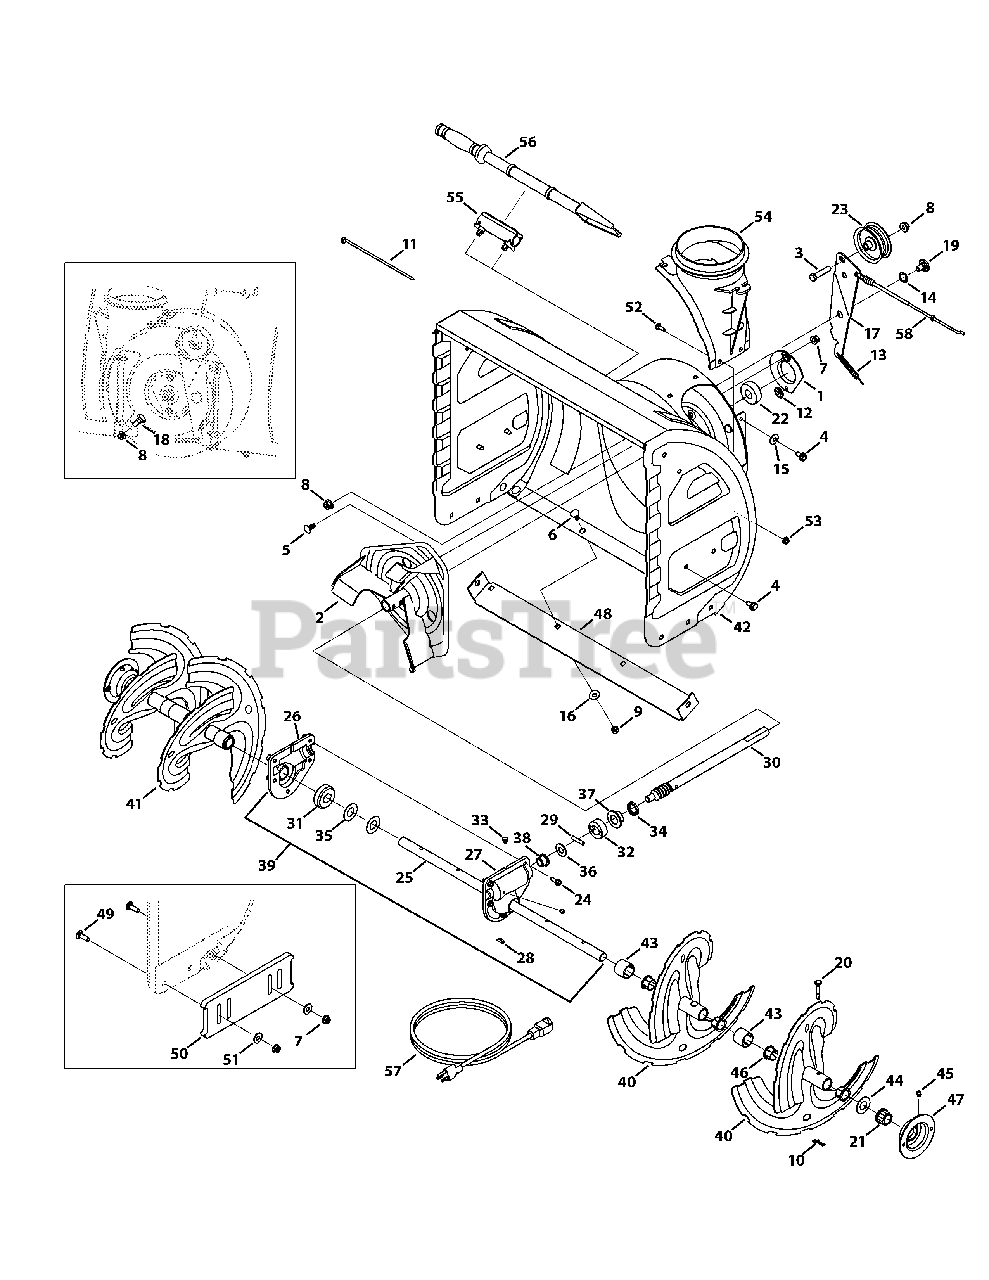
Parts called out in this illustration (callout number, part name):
1	Taptite Screw, 1/4-20 x .750
2	Impeller Assembly, 12" Dia.
3	Hex Screw, 3/8-16 x 1.75
4	Taptite Screw, 5/16-18 x .750
5	Carriage Bolt, 5/16-18 x .750, Grade 5
6	Carriage Bolt, 5/16-18 x .750, Steel
7	Flange Lock Nut, 5/16-18
8	Flange Lock Nut, 3/8-16
9	Hex Nut, 5/16-18
10	Bow-Tie Cotter Pin
11	Cable Tie
12	Push-On Nut, .25 Dia.
13	Extension Spring, .38 OD x 4.59
14	Wave Washer, .625 x .885 x .0175
15	Washer, Bell, .340 x .872 x .060
16	Bell Washer, .340 x .872 x .060, Steel
17	Auger Axle, 26"
18	Shoulder Bolt, 3/8-16 x .496 x .336
19	Shoulder Screw, 3/8-16 x .625 x .17
20	Shear Pin, .25 x 1.50
21	Hex Flange Bearing x .75 ID
22	Flange Ball Bearing, .75 ID x 1.85 OD
23	Flat Pulley, 2.75 OD
24	Bearing Housing, 1.85 ID
25	Auger Idler Bracket
26	Housing Assembly, RH
27	Housing Assembly, LH
28	Hi-Pro Key, 3/16 x 5/8
29	Dowel Pin, .25OD x 1.25
30	Worm Shaft, .75 OD
31	Worm Gear, 20T
32	Thrust Collar, .756 ID x .600
33	Plug, 1/4 x .437
34	Oil Seal, .75 x 1.131 x .188
35	Flat Washer, .760 ID x 1.50 OD
36	Flat Washer, .51 x 1.12 x .06
37	Flange Bearing, .75 ID x 1.00 OD x .59
38	Flange Bearing, .50 ID x .75 OD x .59
39	Gear Box Assembly, 26"; (Incl. Ref. 1, 17, 26 - 38)
40	Spiral Assembly (Left)
41	Spiral Assembly (Right)
42	Auger Housing, 26" Cub
43	Spacer, 1.25OD x .75ID x 1.00
44	Flat washer, .76 x 1.49 x .06
45	Drive Lube Fitting, 3/16
46	Flange Bushing, .800 ID x .910 OD
47	Bearing Housing
48	Shave Plate, 26"
49	Screw, Carriage, 5/16-18 x 1.00
50	Deluxe Shoe
51	Washer, Flat, .349 x .879 x .063
52	Carriage Screw, 1/4-20 x .75
53	Flange Lock Nut, 1/4-20
54	Chute Adaptor, 5" Dia.
55	Cleanout Tool Mount
56	Cleanout Tool
57	Extension Cord
58	Auger Drive Cable
